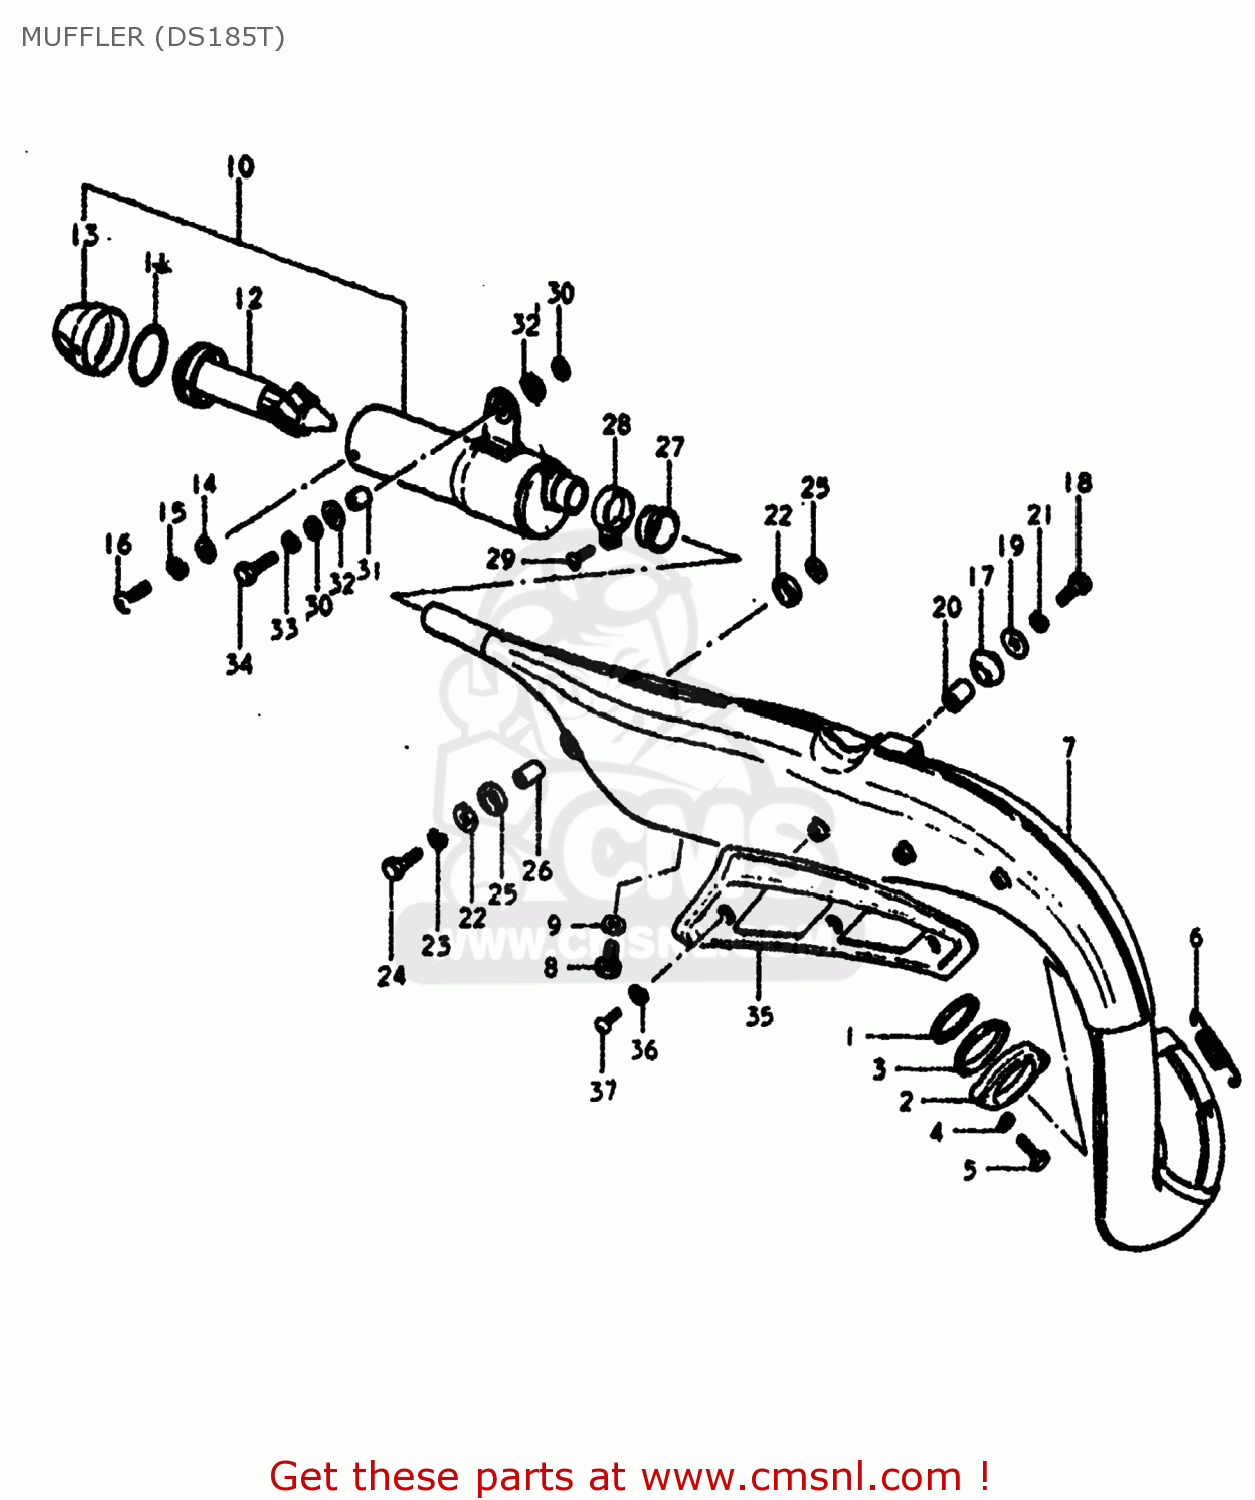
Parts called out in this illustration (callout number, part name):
1	GASKET,EXHAUST PIPE (NAS)
2	CLAMP,EXHAUST PIPE
3	CUSHION,EXHAUST PIPE
4	LOCK WASHER
5	BOLT
6	SPRING
7	BODY,MUFFLER
8	BOLT 10X9
9	GASKET(10X14X3.6) (NAS)
10	MUFFLER ASSEMBLY
11	O-RING (D:3.5 ID:54.4)
12	TUBE,MUFFLER CLEAN OUT
13	COVER,SECOND MUFFLER TAIL
14	WASHER
15	LOCK WASHER
16	SCREW(6X8)
17	DAMPER,MUFFLER,FR
18	BOLT
19	WASHER
20	SPACER (8X12X15)
21	LOCK WASHER
22	WASHER (8.2X20X1.6)
23	LOCK WASHER
24	BOLT
25	CUSHION
26	SPACER (8.6X13.8X9.8)
27	CONNECTOR,MUFFLER
28	CLAMP
29	SCREW
30	WASHER
31	SPACER
32	CUSHION
33	LOCK WASHER
34	BOLT
35	COVER,MUFFLER
36	LOCK WASHER
37	SCREW
